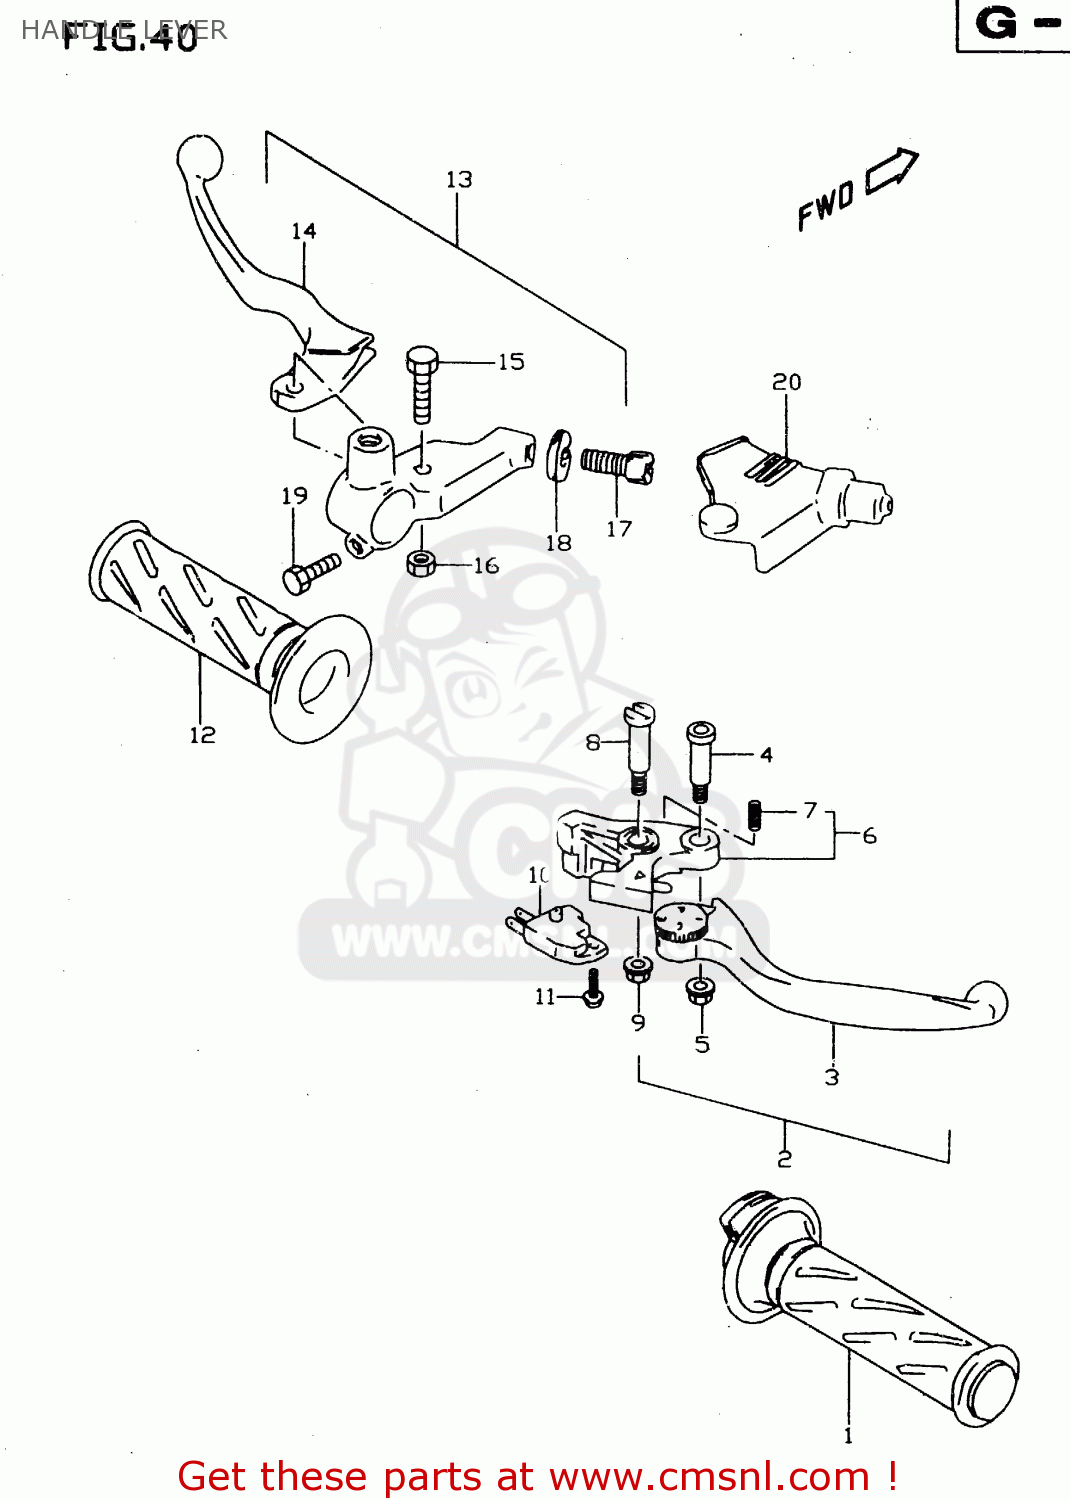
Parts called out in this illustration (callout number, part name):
1	GRIP,THROTTLE
2	LEVER ASSY,BRAKE
3	LEVER,ADJUST
4	BOLT,LEVER
5	NUT
6	KNOCKER
7	SPRING
8	BOLT,LEVER PIVOT
9	NUT
10	SWITCH ASSEMBLY,STOP
11	SCREW
12	GRIP,LEFT
13	LEVER ASSY,CLUTCH
14	LEVER,CLUTCH
15	BOLT,LEVER SET
16	NUT
17	ADJUSTER,CABLE
18	NUT,CABLE ADJUSTER
19	SCREW
20	COVER,CLUTCH LEVER
